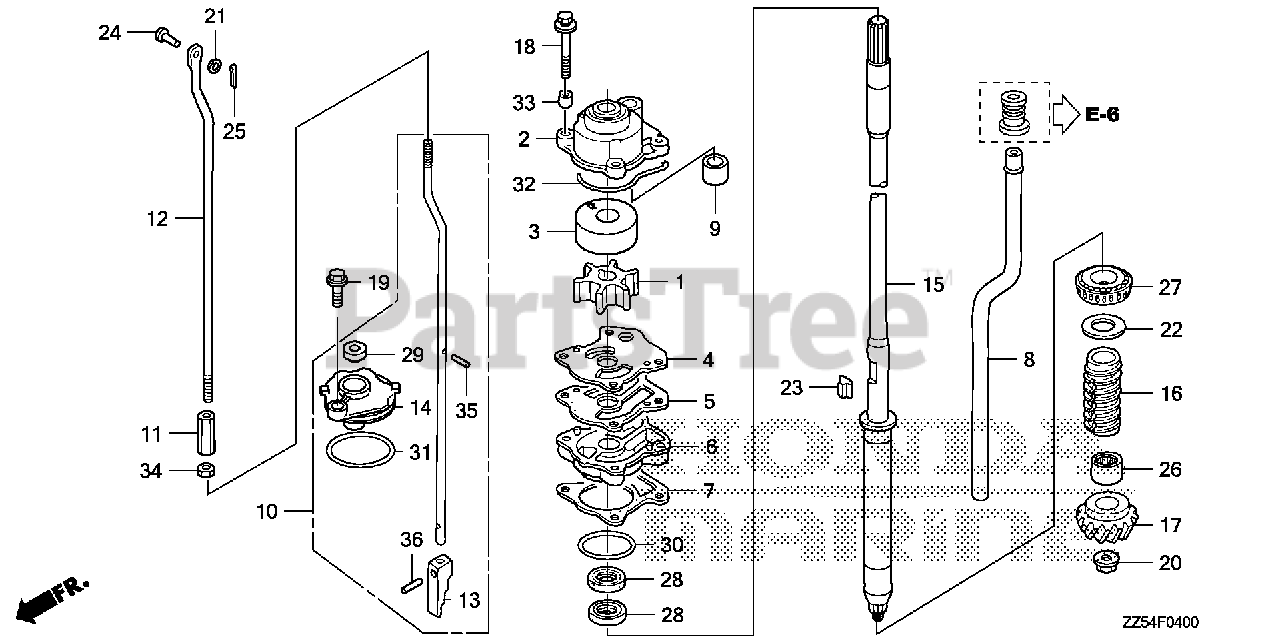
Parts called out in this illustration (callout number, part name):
1	IMPELLER, PUMP
2	HOUSING, IMPELLER
3	LINER, PUMP
4	COVER, IMPELLER
5	GASKET B, IMPELLER
6	HOUSING, WATER PUMP
7	GASKET, WATER PUMP
8	TUBE, WATER
9	RING, WATER TUBE SEAL
10	ROD, SHIFT (L)
11	JOINT, SHIFT ROD
12	ROD A, SHIFT
13	ROD, PUSH
14	HOLDER, SEAL
15	SHAFT, VERTICAL (L)
16	SLINGER, OIL
17	GEAR, PINION
18	BOLT-WASHER (6X40)
19	BOLT, FLANGE (6X20) (ENGINE NO.)
20	NUT, SPECIAL FLANGE (12MM)
21	WASHER, PLAIN (5MM)
22	SHIM, GEAR (40X46X0.10) (A)
22	SHIM, GEAR (40X46X0.15) (B)
22	SHIM, GEAR (40X46X0.30) (C)
22	SHIM, GEAR (40X46X0.50) (D)
23	KEY, WOODRUFF
24	PIN (5X17)
25	PIN, COTTER (1.6MM)
26	BEARING, NEEDLE (7/8X11/8X1)
27	BEARING (25X47X15)
28	SEAL, WATER (17X30X7)
29	SEAL, WATER (7MM)
30	O-RING (41.7X3.5)
31	O-RING (47X3.1)
32	O-RING, WATER PUMP
33	COLLAR, IMPELLER HOUSING
34	NUT, HEX. (8MM)
35	PIN, SPRING (2X12)
36	ROLLER (3X14.8)
